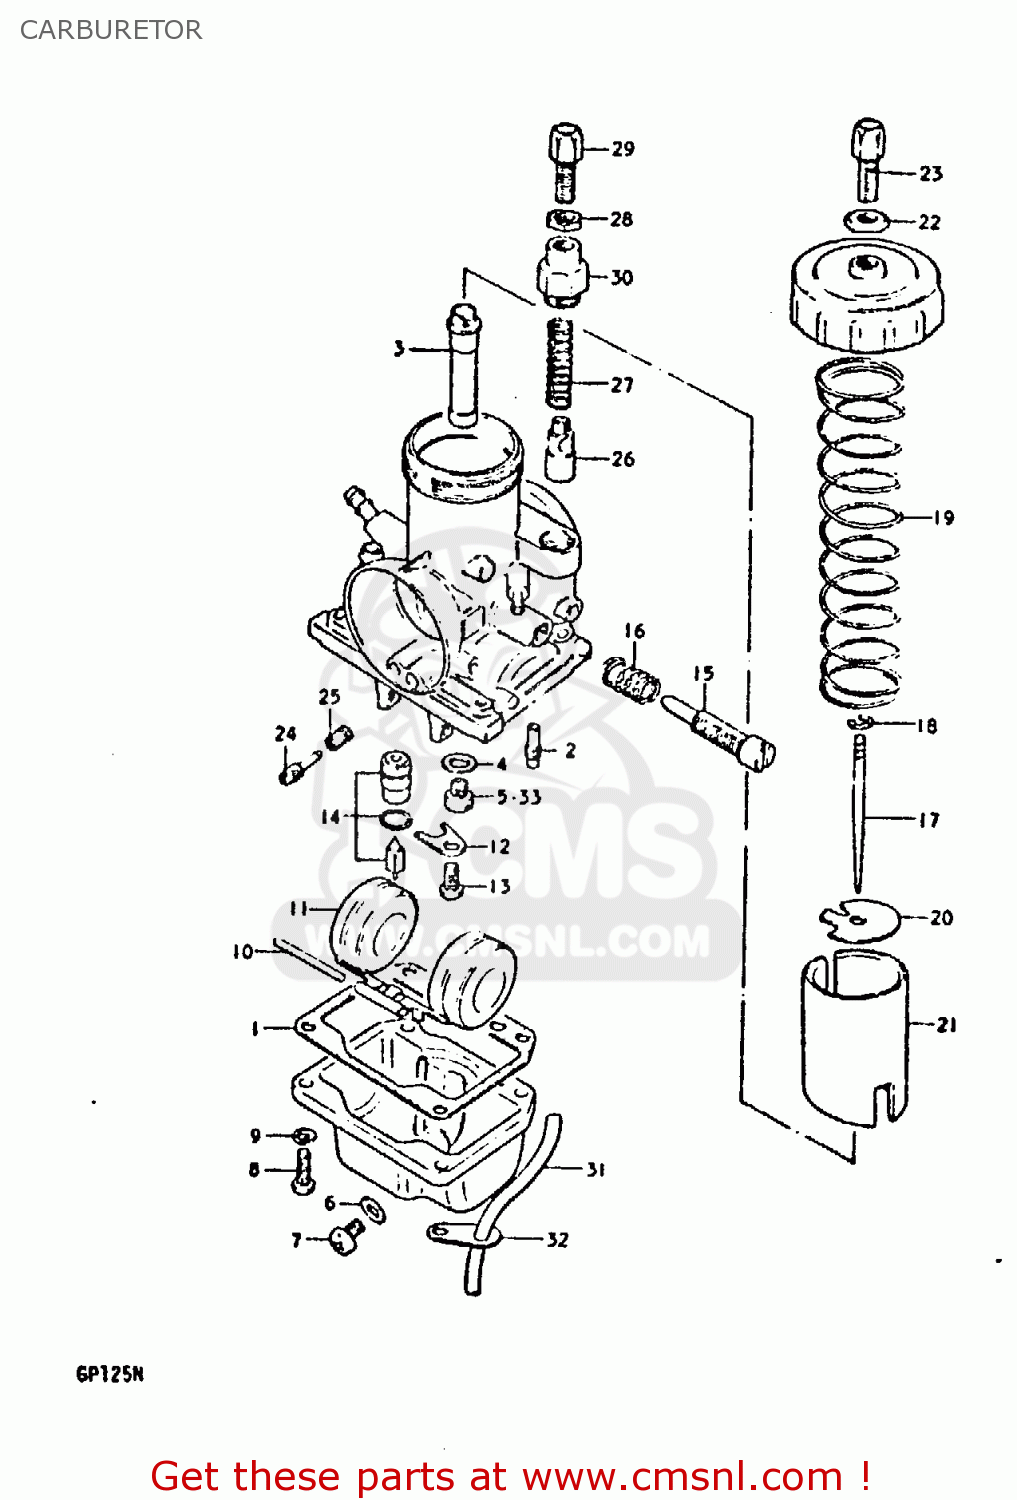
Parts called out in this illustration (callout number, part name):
1	GASKET,FLOAT CAHMBER (NAS)
2	JET
3	JET,NEEDLE
4	WASHER
5	JET
6	GASKET,DRAIN,PLUG (NAS)
7	PLUG
8	SCREW
9	LOCK WASHER
10	PIN,FLOAT
11	FLOAT
12	PLATE
13	SCREW
14	VALVE ASSY, NEEDLE
15	ADJUSTER
16	SPRING,THROTTLE SCREW
17	NEEDLE, JET (4EJ14)
18	CLIP
19	SPRING,THROTTLE VALVE
20	PLATE
21	VALVE,THROTTLE
22	NUT
23	ADJUSTER,CABLE
24	SCREW,PILOT AIR
25	SPRING
26	PLUNGER,STARTER
27	SPRING
28	NUT
29	ADJUSTER,CABLE
30	CAP
31	HOSE
32	PLATE
33	JET
